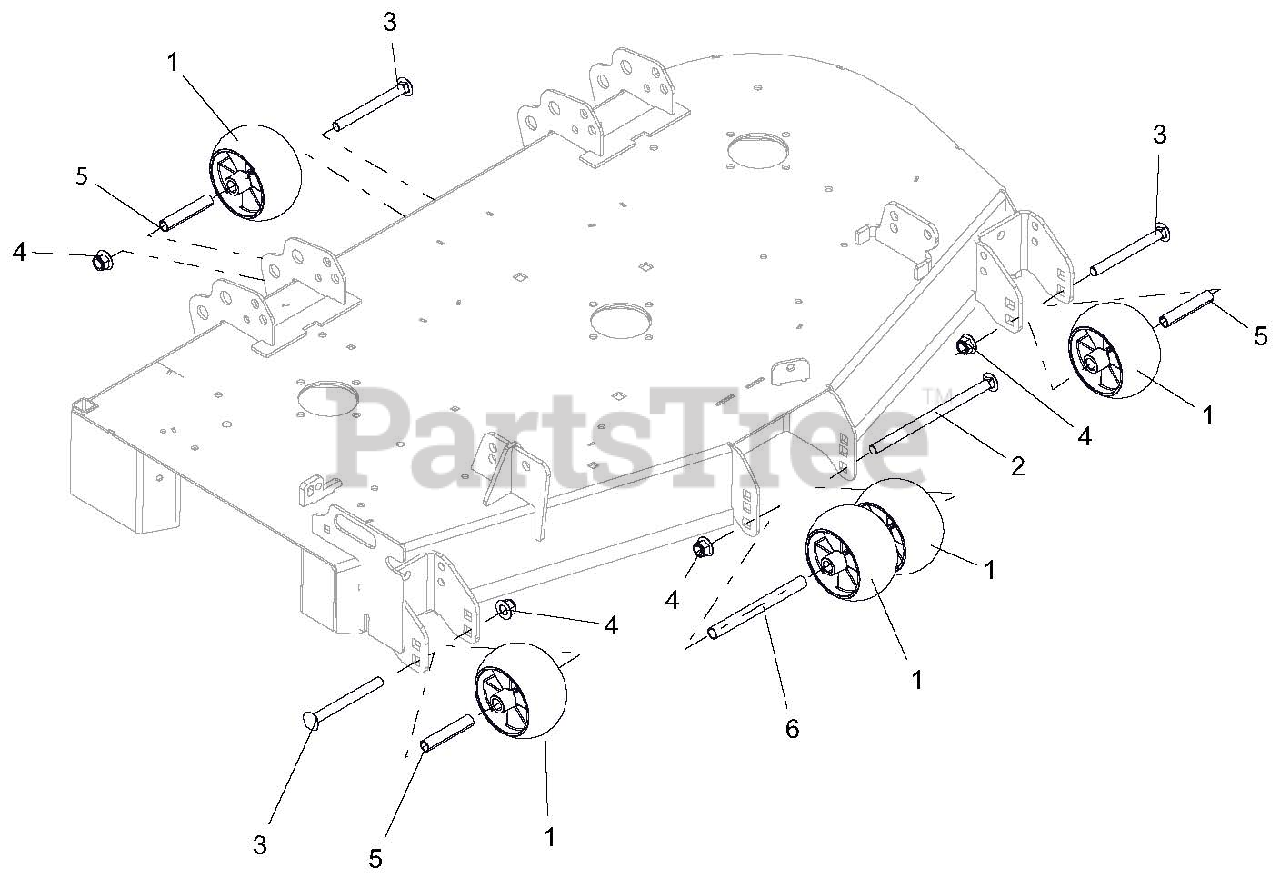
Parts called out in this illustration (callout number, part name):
1	ANTI-SCALP WHEEL - 5X3 CTR
2	BLT-RDHDSQNK .50-13X8.50 Y
3	BLT-RDHDSQNK .50-13X5.00 G5 YWZC
4	NUT-LK-NYL-FLG .50-13 YWZC
5	SPACER, .510X.625X3.35
6	SPACER, .510 X .625 X 6.50
